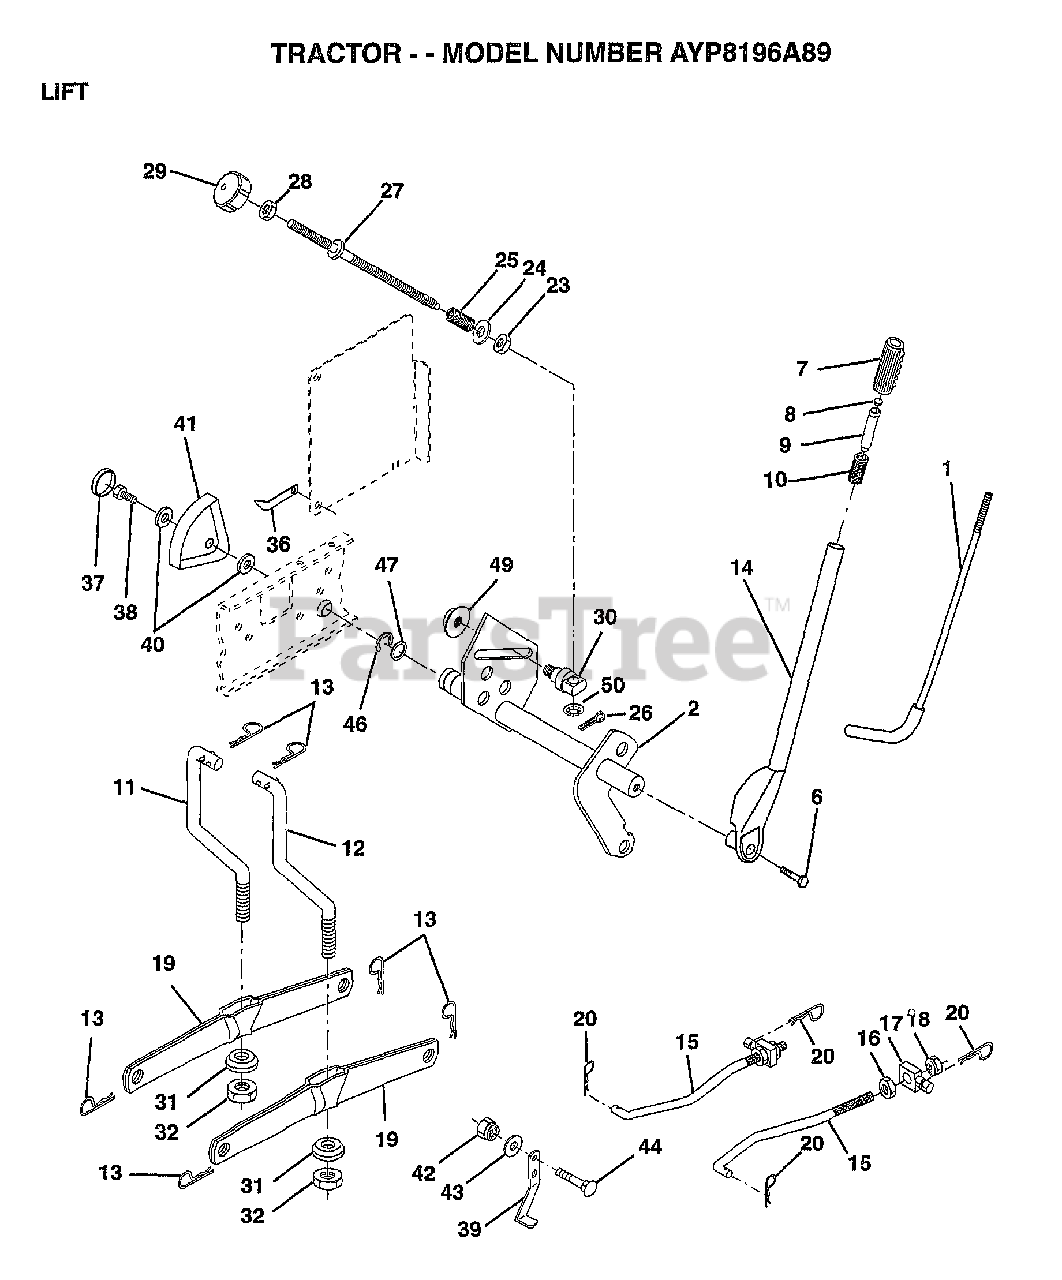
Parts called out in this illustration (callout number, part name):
1	LEVER ROD LT
2	SHAFT LIFT W/IND
6	"BOLT,HEX"
7	GRIP
10	SPRING T
11	LINK.LIFT.LH.GTV
12	LINK.LIFT.RH.GTV.
15	LINK.FRONT
16	NUT
17	TRUNION
18	NUT LTV
19	ARM SUSP REAR
20	RETAINER.SPRING
23	NUT T
24	WASHER
25	SPRING T
28	NUT
29	KNOB INF 3/8-16
30	TRUNNION
31	BEARING PVT LH
32	NUT.CROWNLOCK.3/8
36	POINTER-INDICAT
37	"PLUG,HOLE"
38	SCREW
39	STOP.OVER.CENTER
40	WASHER
41	HEIGHT INDICATOR
43	WASHER GT
44	BOLT
46	E-RING
47	WASHER
49	NUT.HXFLG.LOCK.
